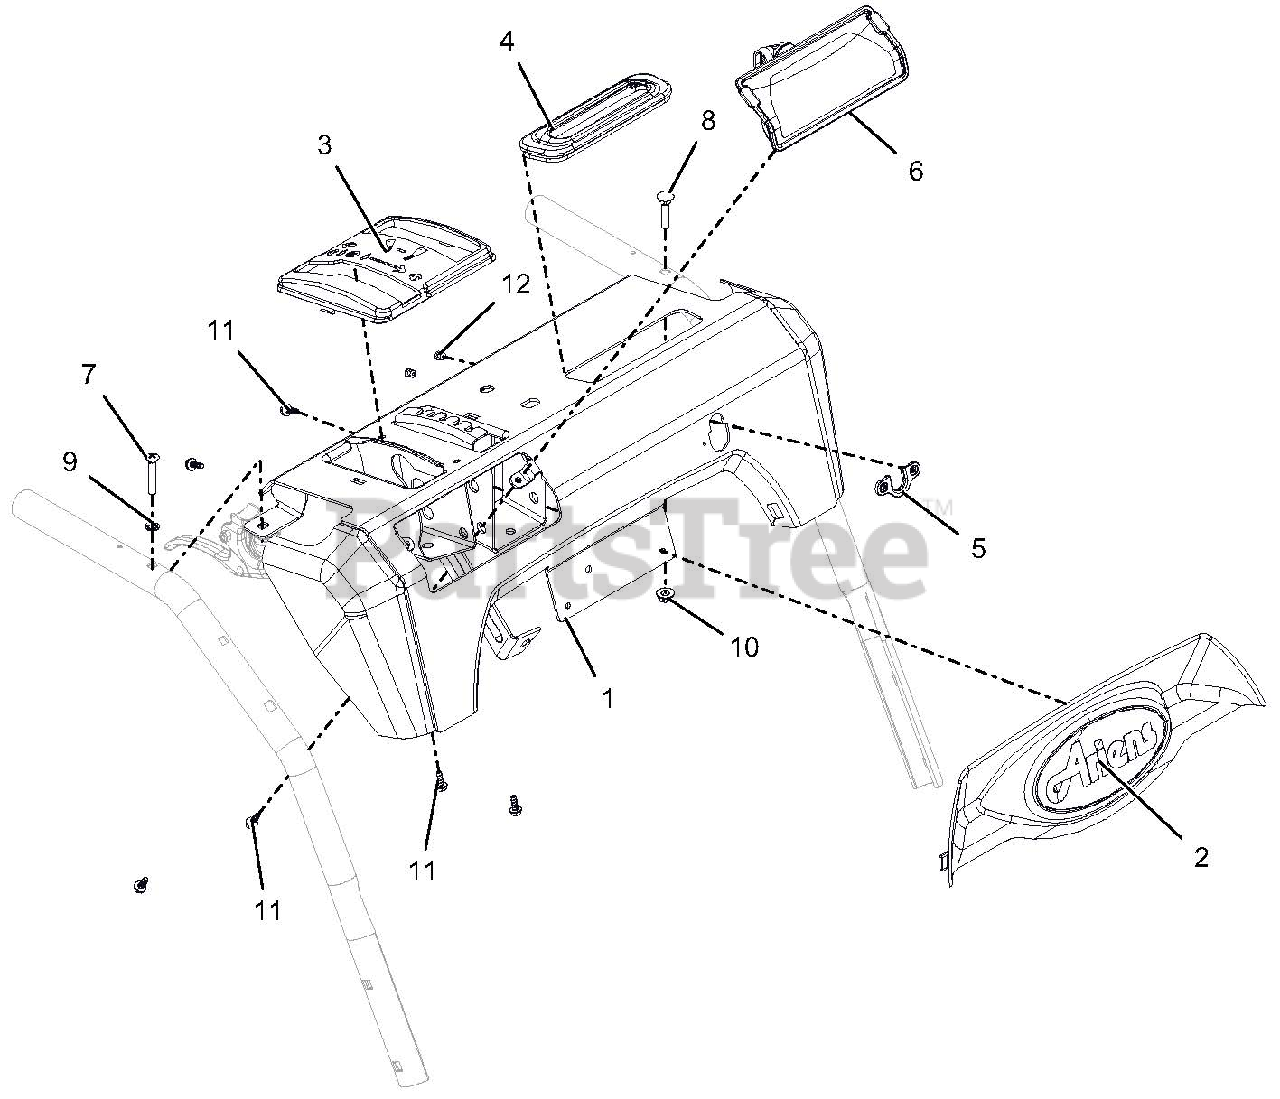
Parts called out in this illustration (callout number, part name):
1	KIT, DASH PANEL W/DECAL HYD TK
2	DASH BEZEL, ARIENS LOGO - PRO
3	SHIFT BEZEL W/ NEUTRAL
4	GROMMET, BOOT, QUICK TURN
5	GROMMET, CABLE, QUICK TURN 2
6	HEADLIGHT ASY, HALO 20W 2SHOT
7	SCR-MCH .25-20X1.50 OVAL HD
8	BLT-RDHDXLSQNK.25-20X1.25 G5ZC
9	WSHR-LK-INT .250 TH TYA
10	@NUT-LK-CTR-FLG .25-20 YWZC
11	SCR-TAP #10X.50 BOSS INDHXHD
12	RVT-POP #43 .125X.313 STL ZINC
